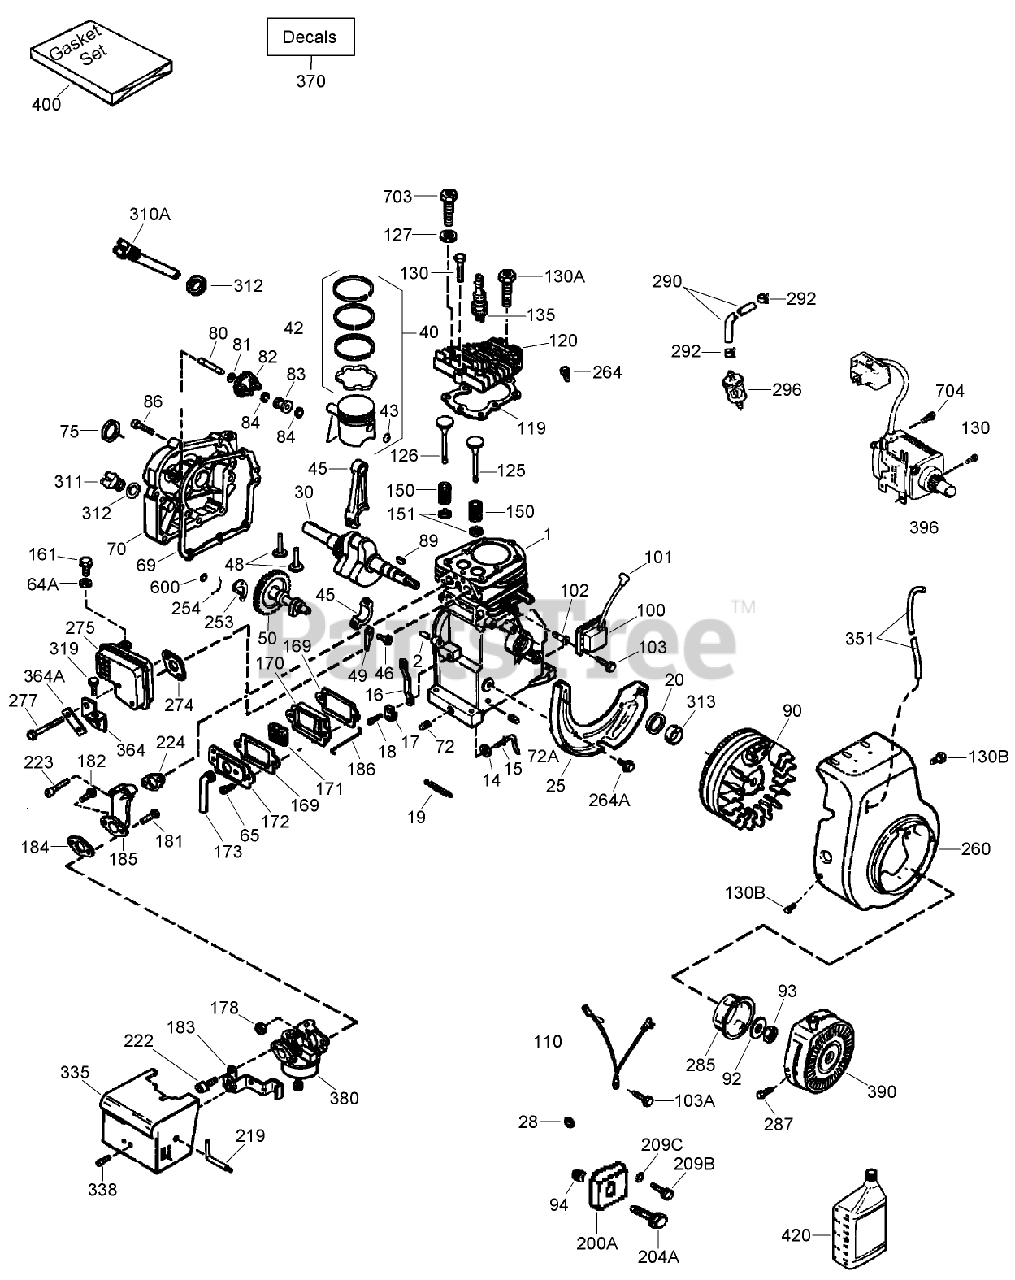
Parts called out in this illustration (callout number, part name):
1	Cylinder Assembly (Incl. Ref. #2, 20, 72
2	Pin-Dowel
14	Washer-Flat
15	Rod-Governor
16	Chute Idler Arm ASM
17	Clamp-Lever, Governor
18	Screw (T-15, 8-32 x 19/64)
19	Spring-Extension
20	Seal-Oil
25	Baffle-Housing, Blower
28	Screw (10-24 x 9/16)
30	Crankshaft
40	Piston, Pin and Ring Set (.010 O S)
40	Piston, Pin and Ring Set (STD)
42	FITTING - TANK 1"
42	FITTING - TANK 3/4"
43	Ring-Retaining, Piston Pin
45	Connecting Rod Assembly (Incl. Ref. #46 49)
46	Bolt-Rod, Connecting
48	Lifter-Valve
49	Dipper-Oil
50	Camshaft (M C R)
64A	Washer
65	Screw (10-24 x 3/4)
69	Gasket-Cover, Cylinder
70	Cover-Cylinder (Includes 75-83, 311)
72	Plug-Drain, Oil (SQH 1/4-18)
72A	Plug-Pipe (Internal Hex, 1/4-18)
75	Seal-Oil
80	Shaft-Governor
81	Washer-Flat
82	Governor Gear ASM
83	Spool-Governor
84	Ring-Retaining
86	Screw (1/4-20 x 1-1/4)
89	Key-Flywheel
90	Flywheel
92	Washer-Belleville
93	Nut-Flywheel
94	Nut (10-32)
100	Ignition-State, Solid
101	Cover-Spark Plug
102	Stud-Mounting, Solid State
103	Screw (T-15, 10-24 x 15/16)
103A	Screw (10-32 x 1/2)
110	Wire-Ground
119	Gasket-Head, Cylinder
120	Head-Cylinder (Includes 130A)
125	Valve-Exhaust (1/32 O S)
125	Exhaust Valve (Std.)(Incl. 151)
126	Valve-Intake 1/32" oversize (Incl. Ref. #151)
126	Valve-Intake Standard (Incl. Ref. #151)
127	Washer-Flat
130	Screw (5/16-18x1-1/2)
130A	Screw (5/16-18 X 2)
130B	Screw (1/4-20 x 1/2)
135	Spark Plug-Resistor (R J19 L M)
